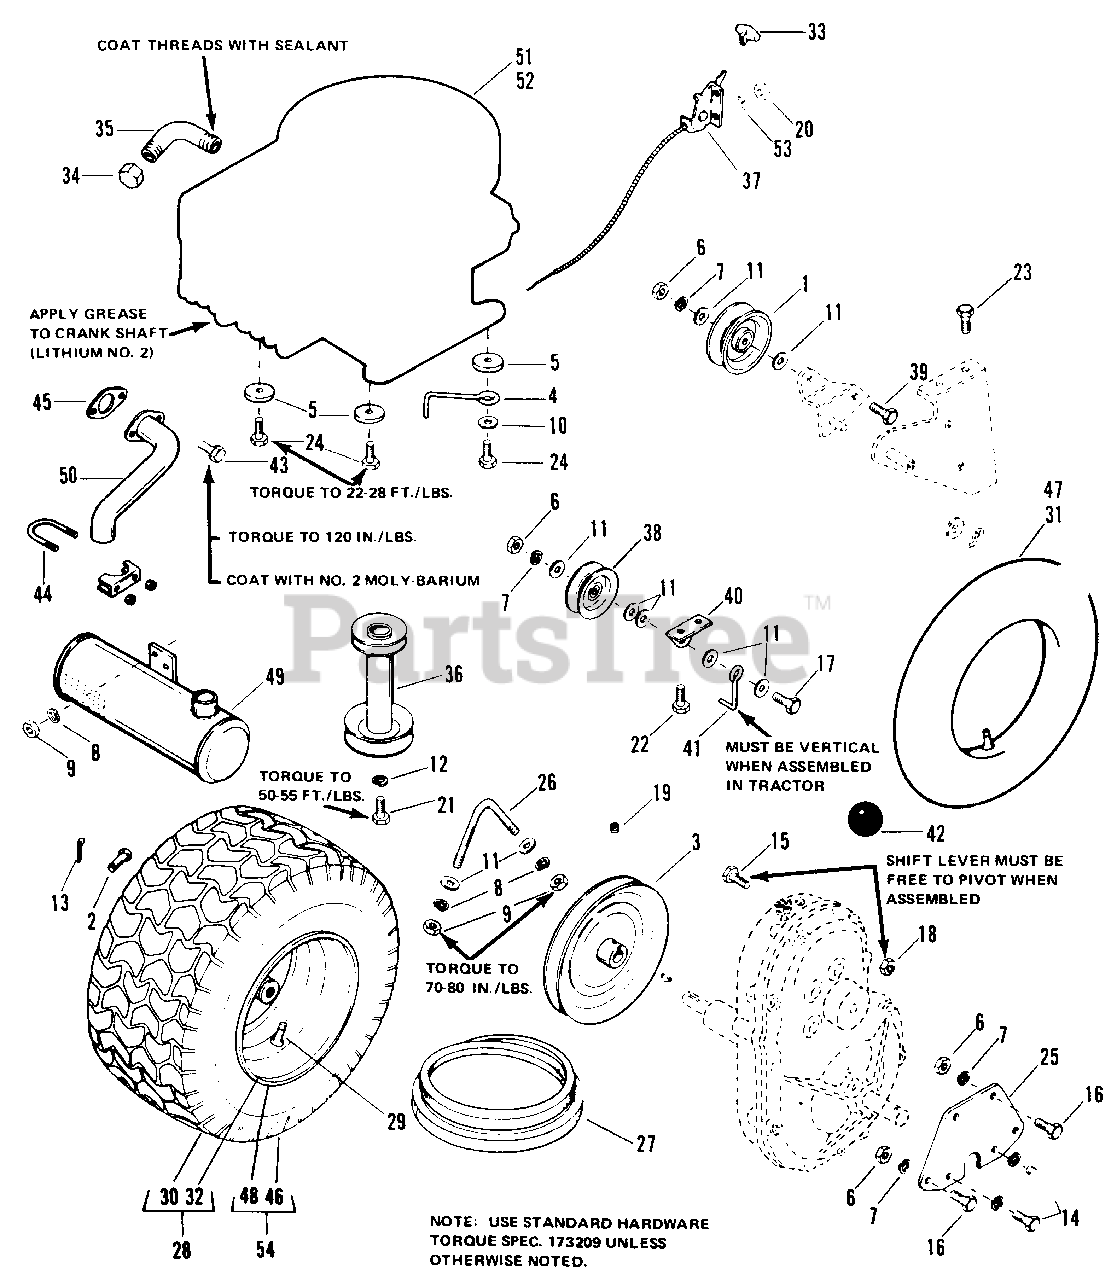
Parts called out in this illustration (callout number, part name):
1	PULLEY, Idler
2	PIN
3	PULLEY, Transmission
6	NUT, Hex 3/8-16
7	LOCKWASHER, Spring, 3/8
8	* LOCKWASHER, Spring, 5/16
9	* NUT, Hex, 5/16-18
10	WASHER, Plain, 3/8
11	WASHER, Plain, 5/16
12	LOCKWASHER, Spring, 7/16
13	PIN, Cotter, 1/8 x 3/4
14	CAPSCREW, Hex Hd., 3/8-16 x 1
15	CAPSCREW, Hex Hd., 1/4-20 x 1
16	CAPSCREW, Hex Hd., 3/8-16 x 3/4
17	CAPSCREW, Hex Hd., 3/8-16 x 1-1/2
18	LOCKNUT, Hex, 1/4-20
19	SCREW, Set Hex Skt., 3/8-24 x 3/8
20	NUT, Plain, 1/4
21	CAPSCREW, Hex Hd., 7/16-20 x 1 1/4
22	SCREW, Hex Washer Hd., 1/4-20 x 3/8
23	SCREW, Hex Washer Hd., 5/16-18 x 5/8
24	SCREW, Hex Washer Hd., 3/8-16 x 3/4
25	SUPPORT, Bracket
26	BOLT, Axle
27	V-BELT, Drive
28	WHEEL & TIRE ASSY, 18 x 9.50-8 (6008)
29	VALVE, Stem & Cap (6008, 6010)
30	TIRE (6008)
31	TUBE (6008)
32	WHEEL ASSY (6008)
33	KNOB
34	PIPE, Cap, 3/8
35	OIL DRAIN PIPE
36	PULLEY ASSY, Engine
37	CONTROL ASSY
38	PULLEY, Idler
39	CAPSCREW, Hex Hd., 3/8-16 x 1 1/4
40	BRACKET, Idler
43	SCREW, Hex Whiz Lock, 5/16-18 x 3/4 (6010)
44	CLAMP, Exhaust 1 1/4 (6010)
45	GASKET, Muffler
46	TIRE, Tubeless (6010)
47	TUBE (6010)
48	WHEEL, 6" x 10" D (6010)
49	MUFFLER (6010)
50	PIPE, Exhaust (6010)
53	LOCKWASHER, 1/4
54	WHEEL & TIRE ASSY, 20 x 8.00-10 (6010)
